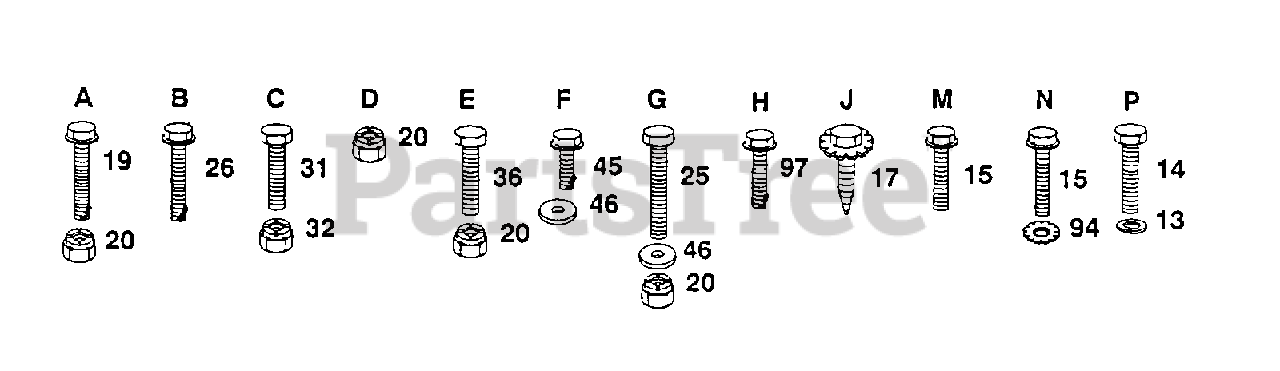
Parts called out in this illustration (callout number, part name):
13	LOCKWASHER
14	SCREW HEX HD CAP
15	SCREW
19	BOLT
25	BOLT
26	SCREW
31	BOLT
45	SCREW
46	WASHER
94	LOCKWASHER
97	SCREW LT
